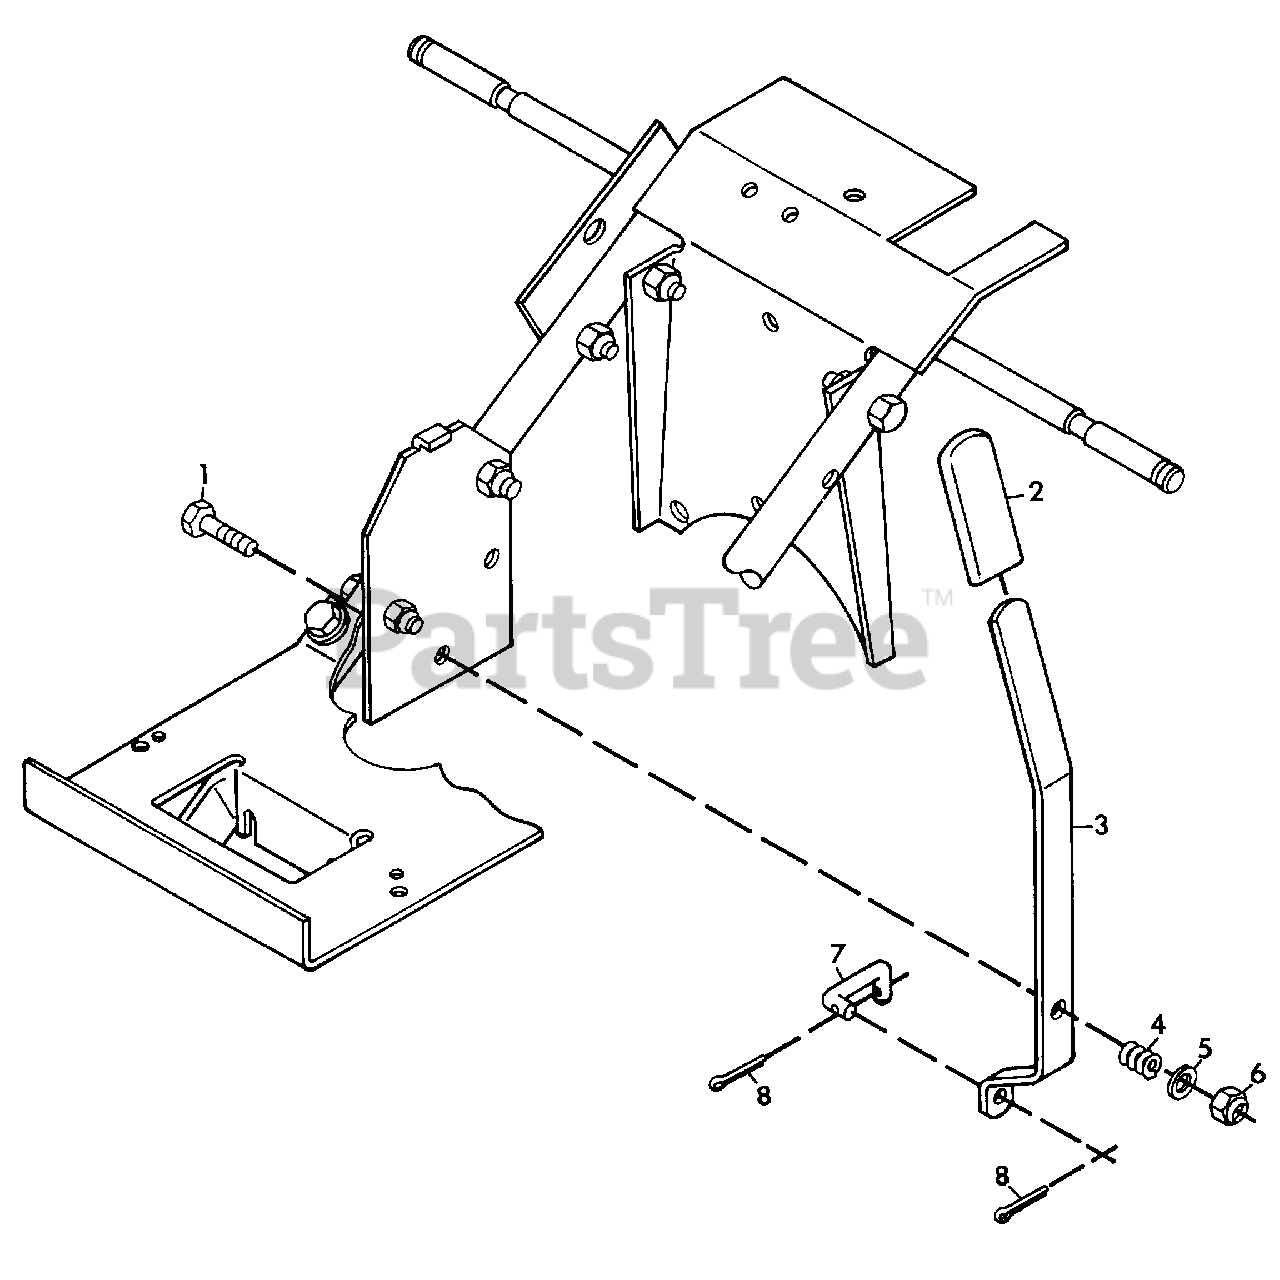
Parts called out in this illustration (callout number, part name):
1	BOLT, HEX 3/8-16X1.75
2	GRIP, HANDLE
3	LEVER, HI-LO
4	SPRING, COMP. 1X.78
5	WASHER, FLAT .406X.812X.065
6	NUT, LOCK 3/8-16
7	ROD, HI-LO
8	PIN, COTTER .09X1.00
